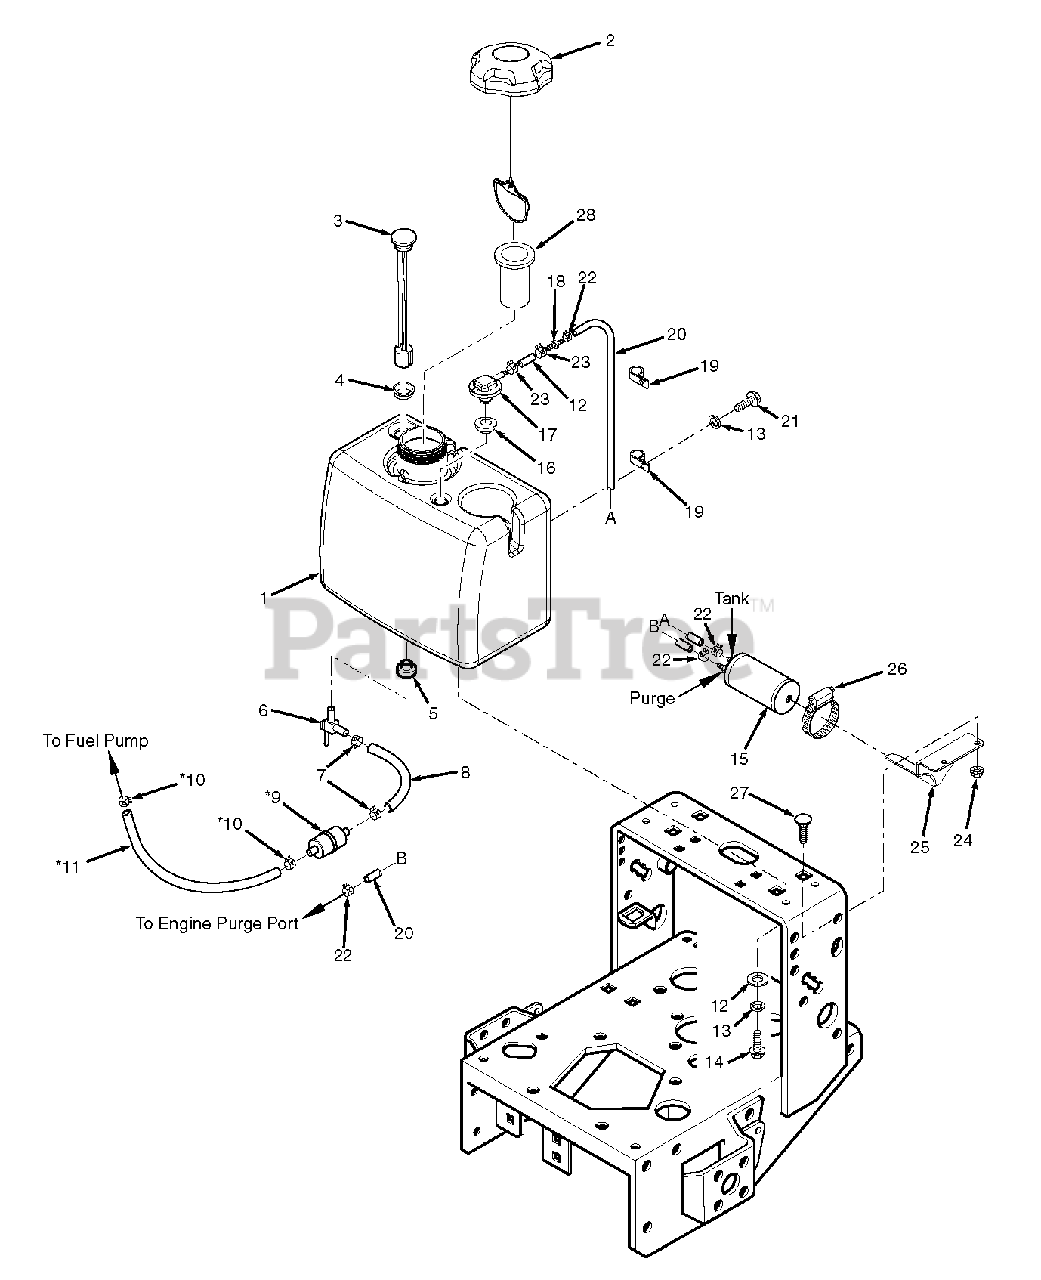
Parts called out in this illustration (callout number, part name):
1	Fuel Tank Assembly
2	Fuel Cap w/ Tether
3	Fuel Gauge Assembly
4	Seal, Fuel Gauge
5	Bushing, .56 Dia. Viton
6	Ball Valve w/Screen
7	Clamp, Fuel Hose
8	Fuel Hose, 1/4' ID
9	Fuel Filter
10	Clamp, Fuel Hose
11	Fuel Hose
12	Hose, Vapor Recovery 1/4'
13	Lockwasher, 5/16' Spring
14	Bolt, Hex Head 5/16-18 x 1'
15	Carbon Canister
16	Grommet, Viton,
17	Fitting, Remote Vent
18	Mender, 1/4 x 3/16 w/.02 Hole
19	Clamp, 3/8'
20	Hose, Vapor Recovery 3/16'
21	Bolt, Hex Head 5/16-18 x 3/4'
22	Clamp, Vapor Recovery Hose 3/16'
23	Clamp, Fuel Hose 7/32' ID
24	Nut, Serrated Flange 5/16-18
25	Bracket, Canister Mounting
27	Bolt, Carriage 5/16-18 X 1'
28	Tube, Fuel Tank Insert - 4'
